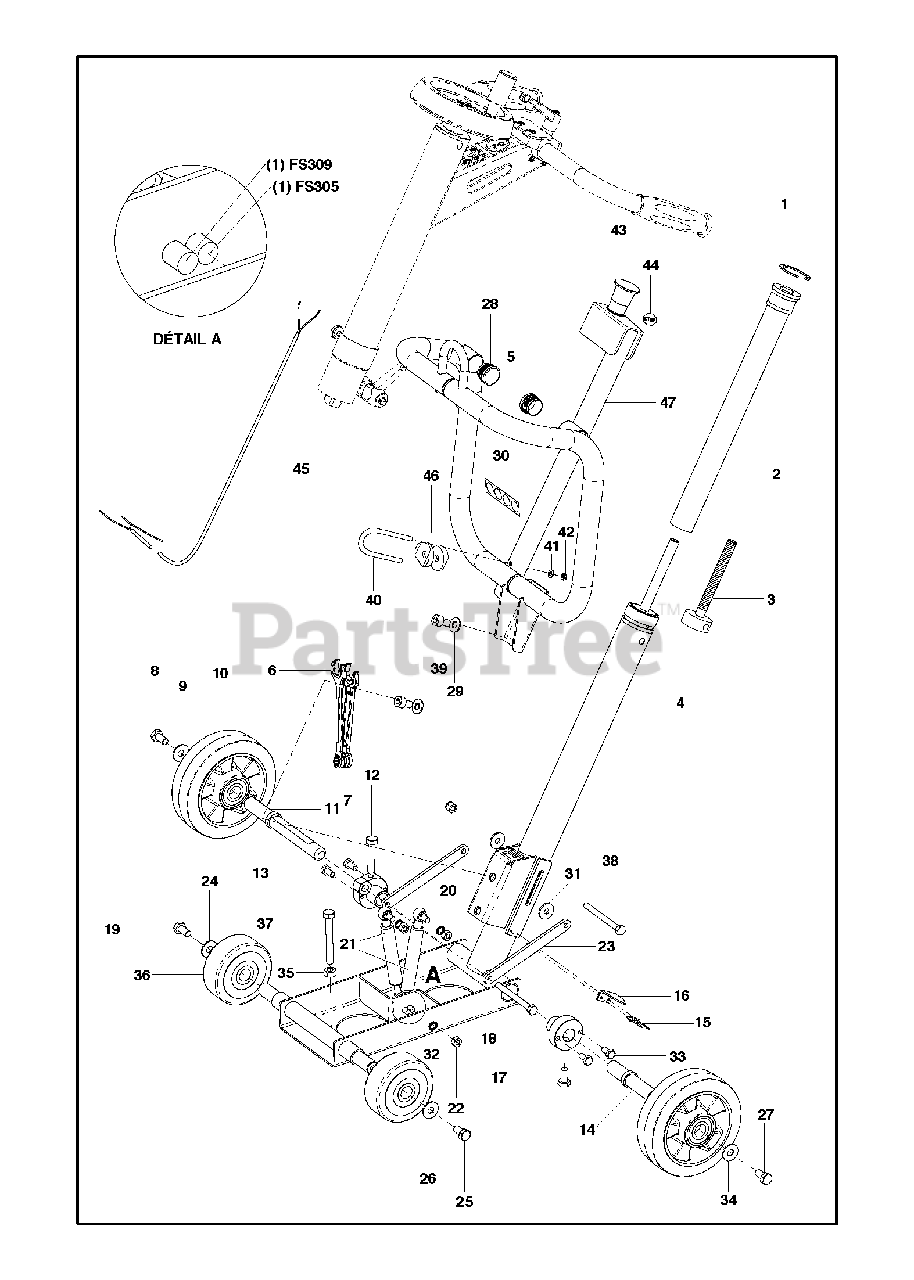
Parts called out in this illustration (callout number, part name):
13	SCREW EHHM
19	SCREW EHHM
20	HEXAGON NUT
22	HEXAGON NUT
29	WASHER
42	HEXAGON LOCKING NUT
